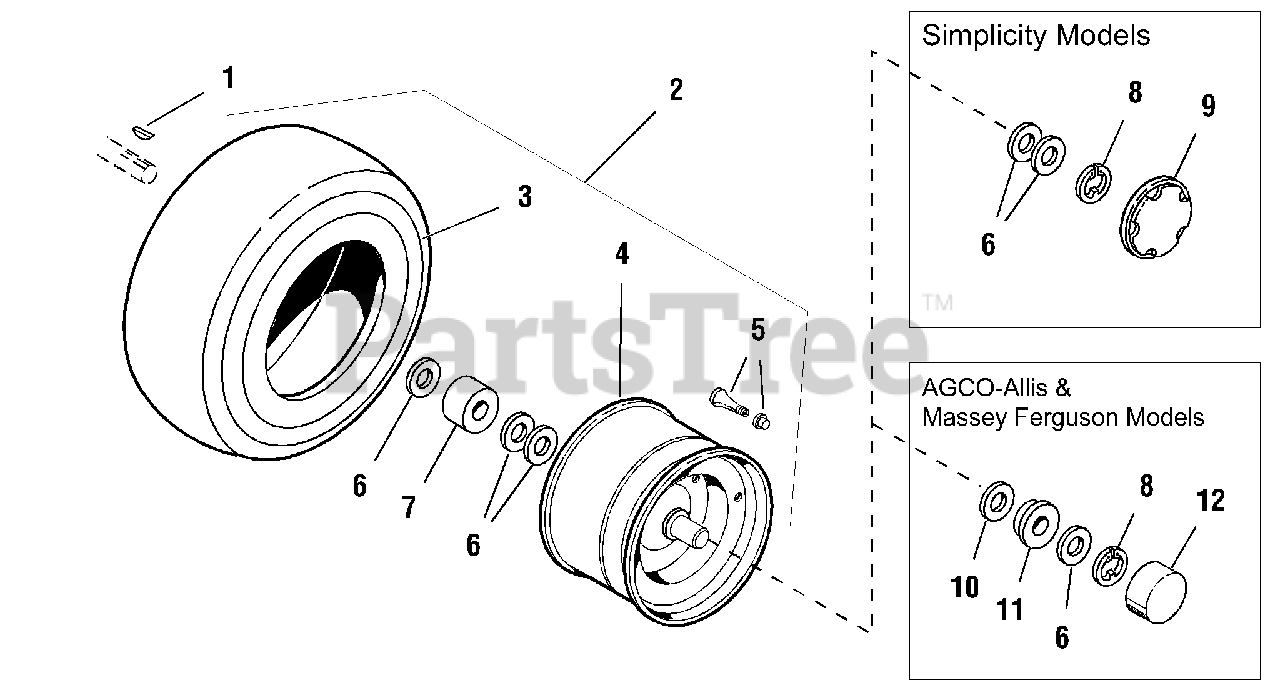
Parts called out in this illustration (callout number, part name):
1	KEY
2	REAR WHEEL & TIRE ASSY - 16HP Models
2	REAR WHEEL & TIRE ASSY - 14HP Models
3	TIRE, Turf Trac, 18 x 8.50-8" - 14HP Models
3	TIRE, Turf Trac, 20 x 8.00-8" - 16HP Models
4	WHEEL, Metallic Gray, 8", Rear
5	VALVE STEM & CAP
6	WASHER
7	SPACER
9	HUB CAP, 7-3/4" Black, Rear Scalloped
10	WASHER
11	RETAINER, Cap
12	CAP, Axle
